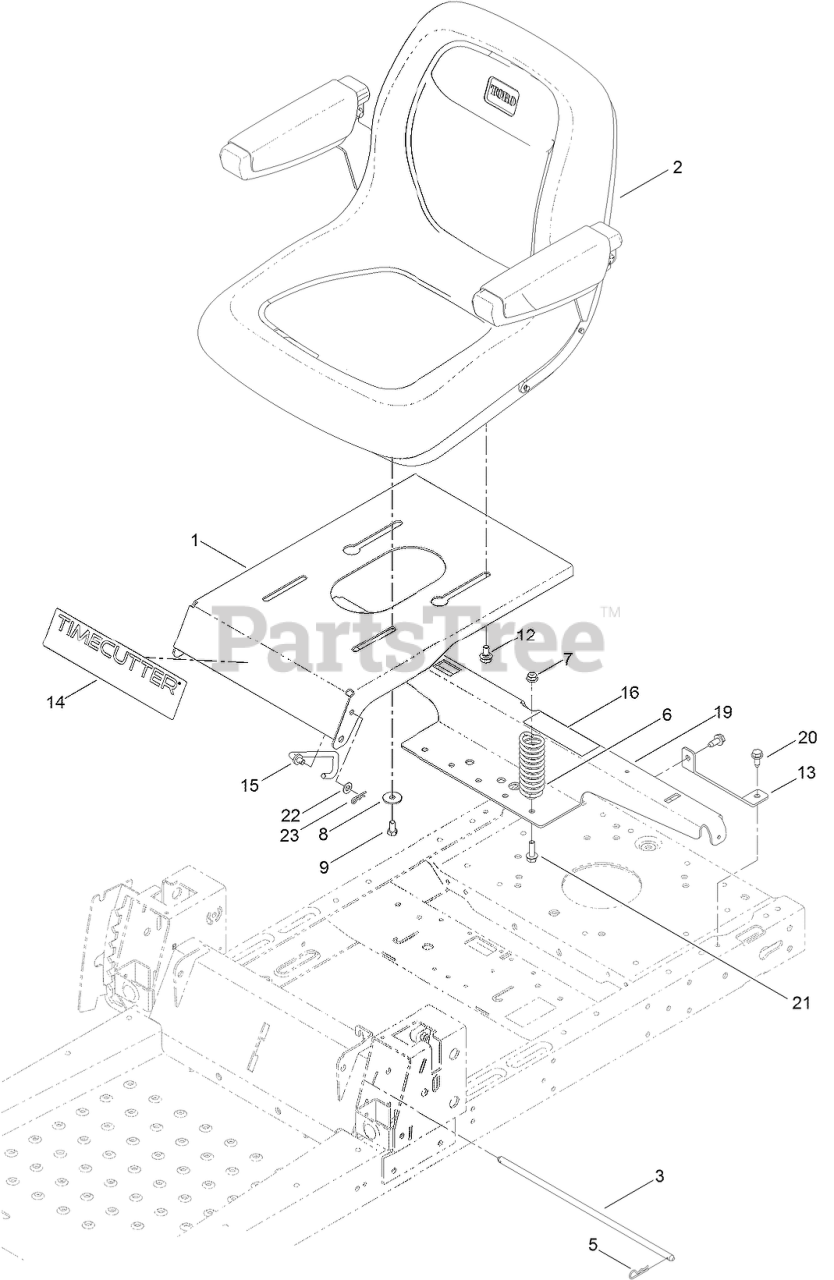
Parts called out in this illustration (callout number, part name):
1	PAN-SEAT
2	SEAT-18 Inch
3	ROD-PIVOT, NARROW
5	PIN-COTTER
6	SPRING-COMPRESSION
7	NUT-HF, NI
8	WASHER-PIVOT
9	SCREW-HH
12	BOLT-SHOULDER
13	SUPPORT-TANK, REAR
14	DECAL-TIMECUTTER
15	STOP-SEAT
16	DECAL-SERVICE, CE
19	SUPPORT-POD
20	SCREW-HWHTF
21	SCREW-HHF
22	WASHER-PLAIN
23	PIN-COTTER
